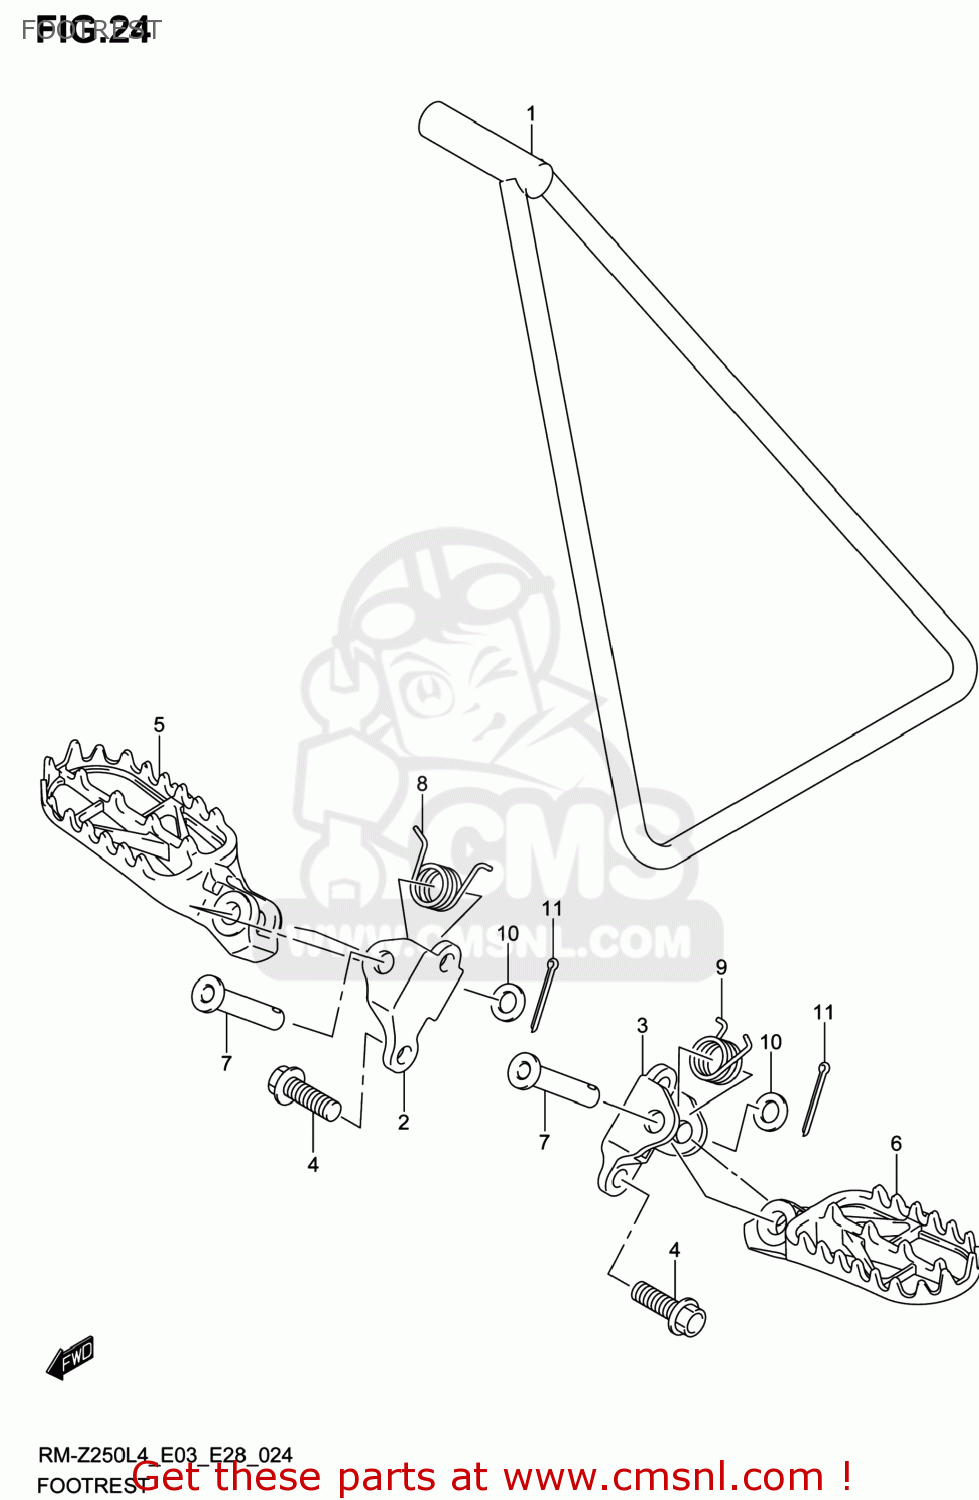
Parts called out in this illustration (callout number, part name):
1	STAND
2	BRACKET,FOOTREST,R
3	BRACKET,FOOTREST,L
4	BOLT(10X25)
5	FOOTREST,R
6	FOOTREST,L
7	PIN(10X41.5)
8	SPRING,FOOTREST,R
9	SPRING,FOOTREST,L
10	WASHER(10.5X18X1)
11	PIN
